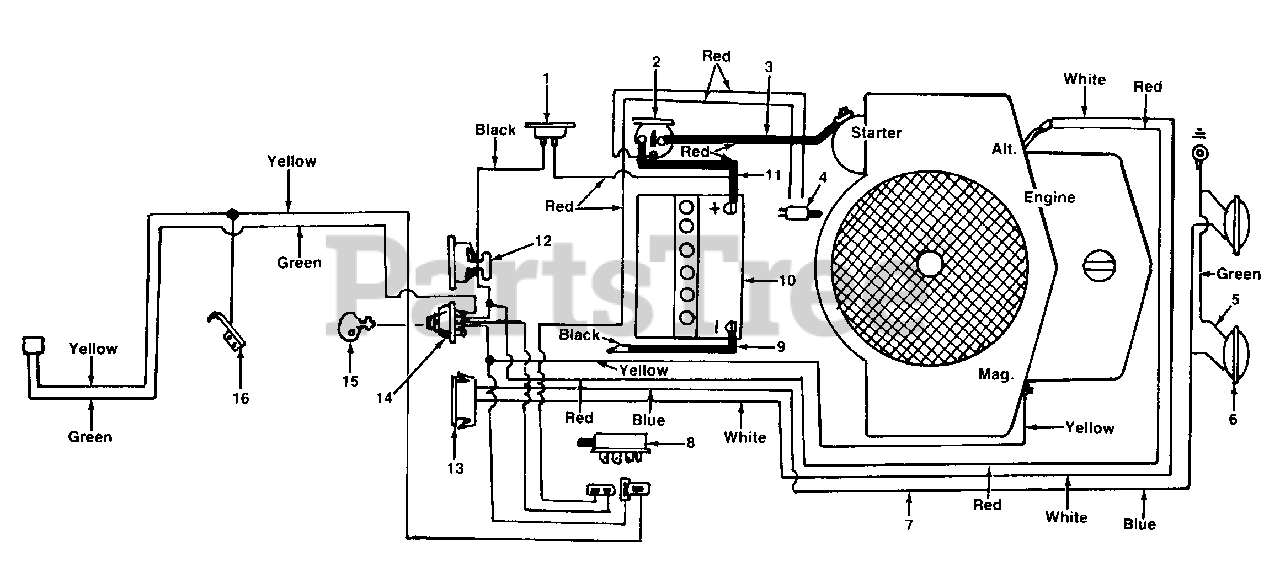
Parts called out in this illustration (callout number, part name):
1	Circuit Breaker
2	Solenoid
3	Wire
4	Safety Switch
5	Ground Wire
6	Head Light
7	Wire Harness
8	Safety Switch
9	6 Ga. Black Wire
10	Battery 12V
12	Ammeter
13	Light Switch
14	Ignition Switch
15	Ignition Key
16	Spring Switch
